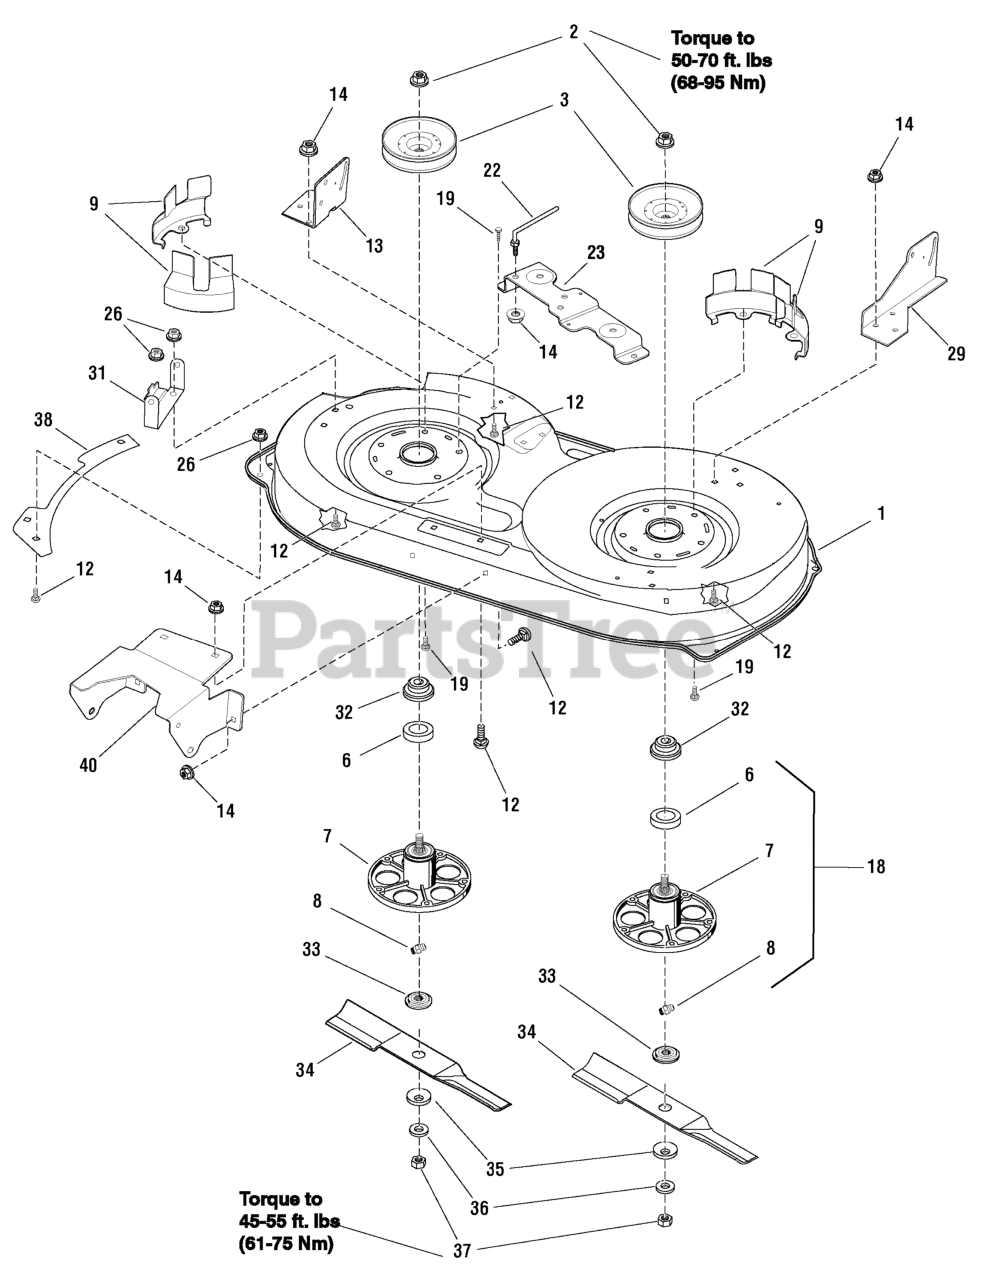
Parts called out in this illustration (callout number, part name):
1	HOUSING, Mower Deck, 38 in
2	NUT, Nylock Ring, Pulley 9/16-18
3	PULLEY, Jackshaft
6	BALL BEARING, Jackshaft
7	JACKSHAFT HOUSING
8	FITTING, Lubrication
9	BELT GUIDE
12	BOLT, Carriage 5/16-18 x 5/8
13	BRACKET, Right Suspension
14	NUT, 5/16-18
18	JACKSHAFT HOUSING ASSEMBLY
19	BOLT, 3/8-16 x 1-1/4
22	BELT GUIDE (5/16-18)
23	BRACKET, Brake Mounting 38 in
26	NUT, Hex Flange Lock, 5/16-18
29	BRACKET, Left Suspension
31	BRACKET, Hinge
32	SPACER, Pulley
33	BLADE ADAPTER
34	BLADE, 38 in
35	WASHER, Belleville
36	WASHER, Hardened
37	NUT, Blade, 9/16-18
40	BRACKET, Front Hanger
